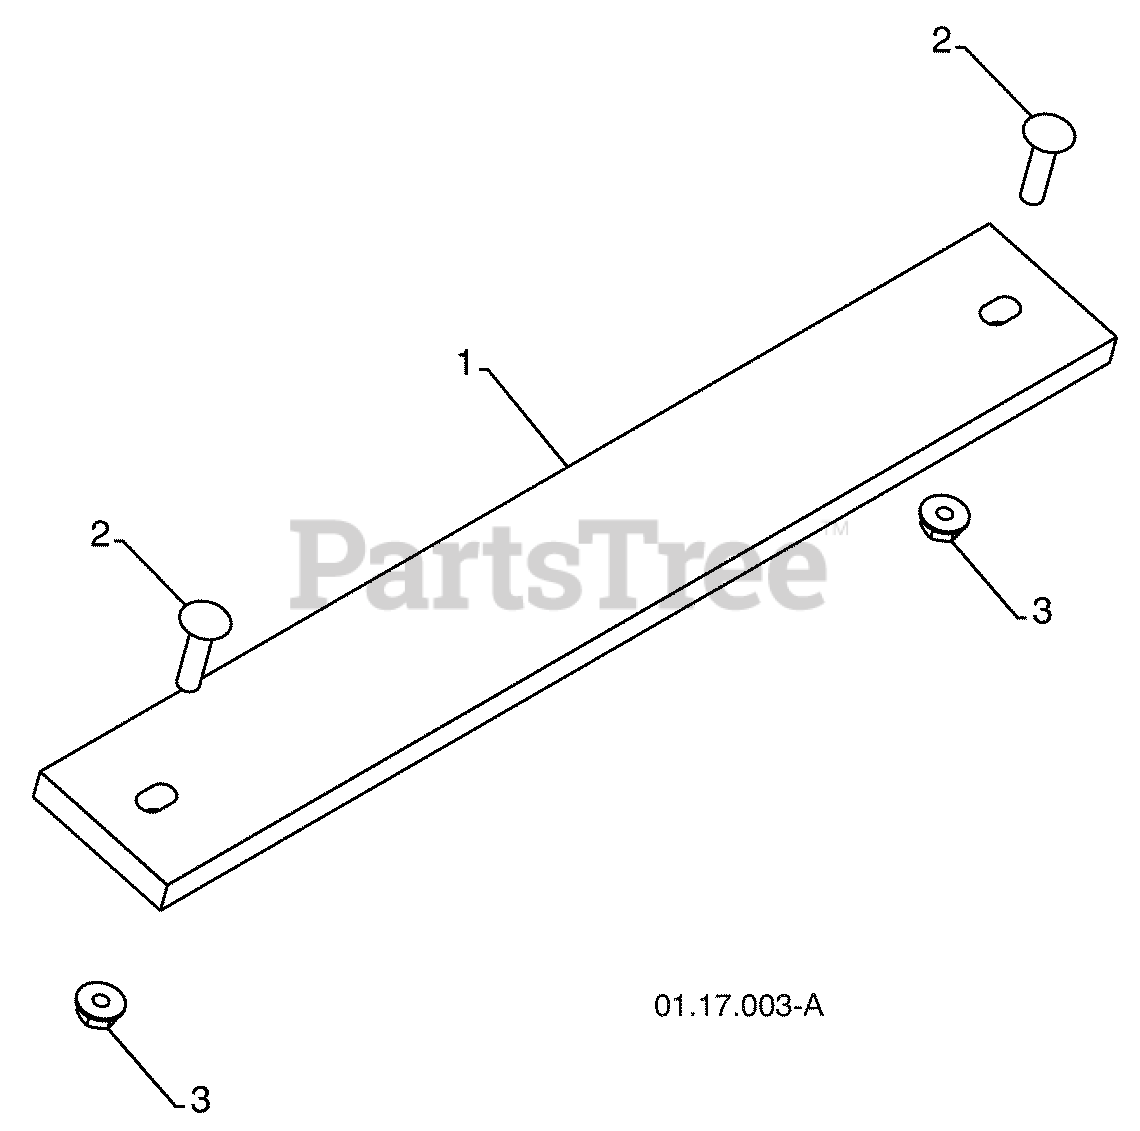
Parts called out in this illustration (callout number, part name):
1	WEIGHT BAR
2	CARRIAGE BOLT 5/16-18 X 1.25
3	NUT 5/16-18
